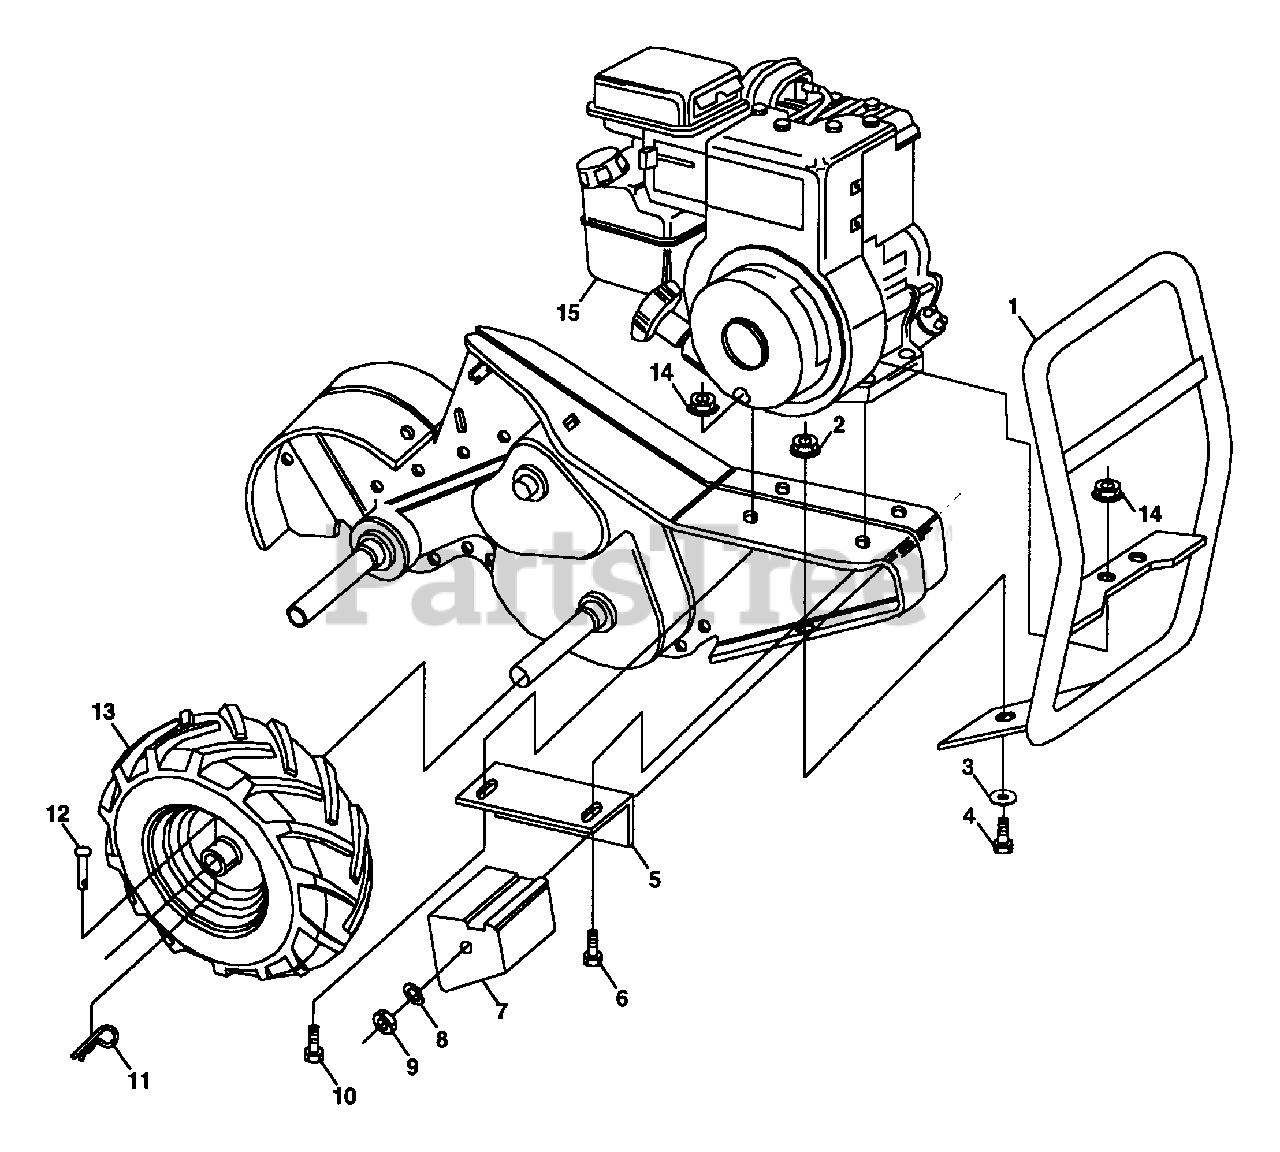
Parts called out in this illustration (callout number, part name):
2	Locknut, Hex, Flange 5/16-18
3	Washer 11/32 x 11/16 x 16 Ga.
4	Bolt, Hex 5/16-18 x 3/4
5	Bracket, Reinforcement
6	Bolt, Hex 5/16-18 x 2
7	Counter Weight, R.H.
8	Washer, Lock 3/8
9	Nut, Hex 3/8-16
10	Bolt, Hex 5/16-18 x 1-1/2
11	Clip, Hairpin
12	Rivet, Drilled
13	Rim
13	Tire Valve
14	Nut, Keps 5/16-18
15	Engine
